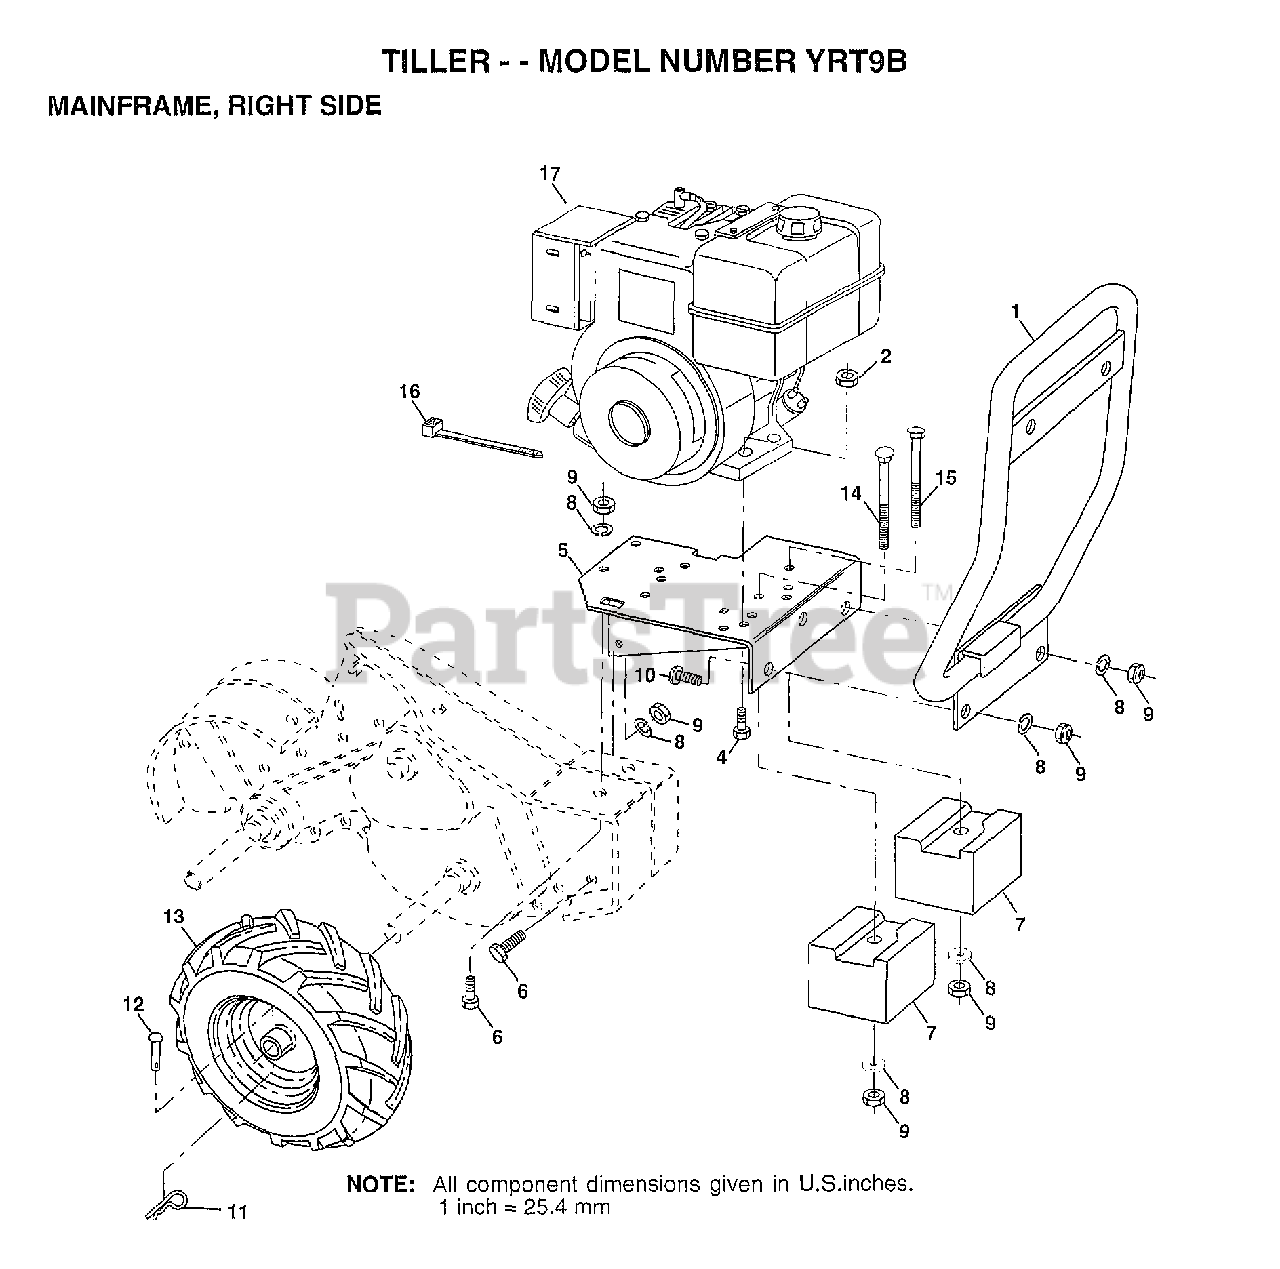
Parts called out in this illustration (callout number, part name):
1	BUMPER.ASM
4	BOLT
5	"ASM. ENGINE, BASE"
6	BOLT
7	COUNTERWEIGHT CRT
8	LOCKWASHER
9	NUT.HEX.3/8-16UNC
11	SPRING.RETAINER
12	RIVET.PAN HD.1.75
13	TIRE TI
13	WHEEL TI
14	BOLT CRT
15	BOLT.3/8-16X4.5
16	WIRE TIE
